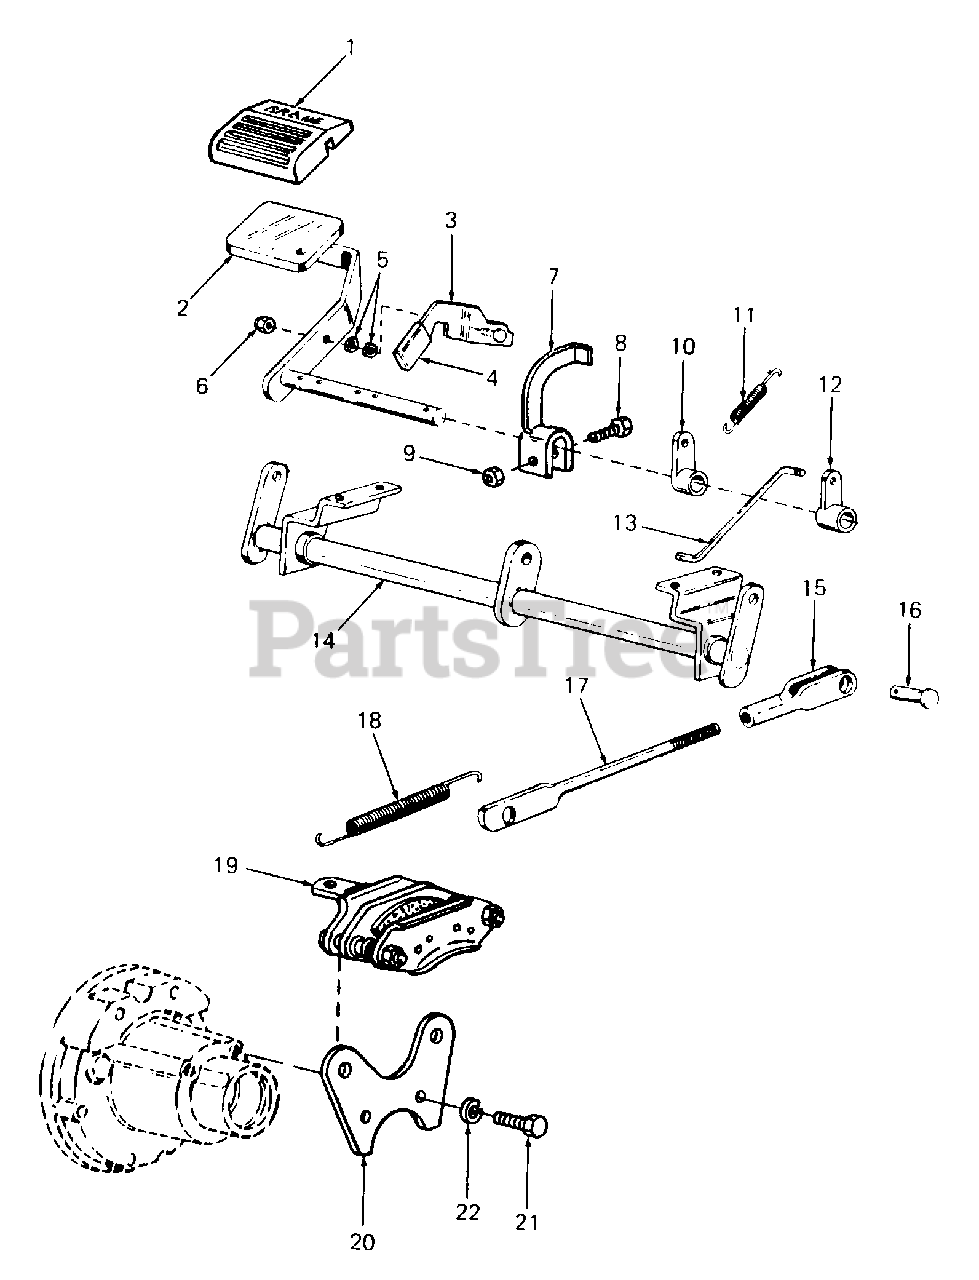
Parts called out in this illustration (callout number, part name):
1	Pad, Brake Pedal
2	Pedal Assy, Brake
5	Washer, Wave, 1/4 Dia
6	Nut, Hex Insert Lock, 1/4-20
9	Nut, Hex Center Lock, 1/4-20
11	Spring, Return
15	Clevis, Adjustment
16	Pin, Clevis, 3/8 Dia X 1.0 Lg
17	Rod, Brake
18	Spring, Tension
19	Kit, Brake Caliper
20	Bracket, Brake Mounting
21	Screw, Hex Cap, 5/16-18 X 1.0 Lg GR5
22	Washer Lock 5/16
